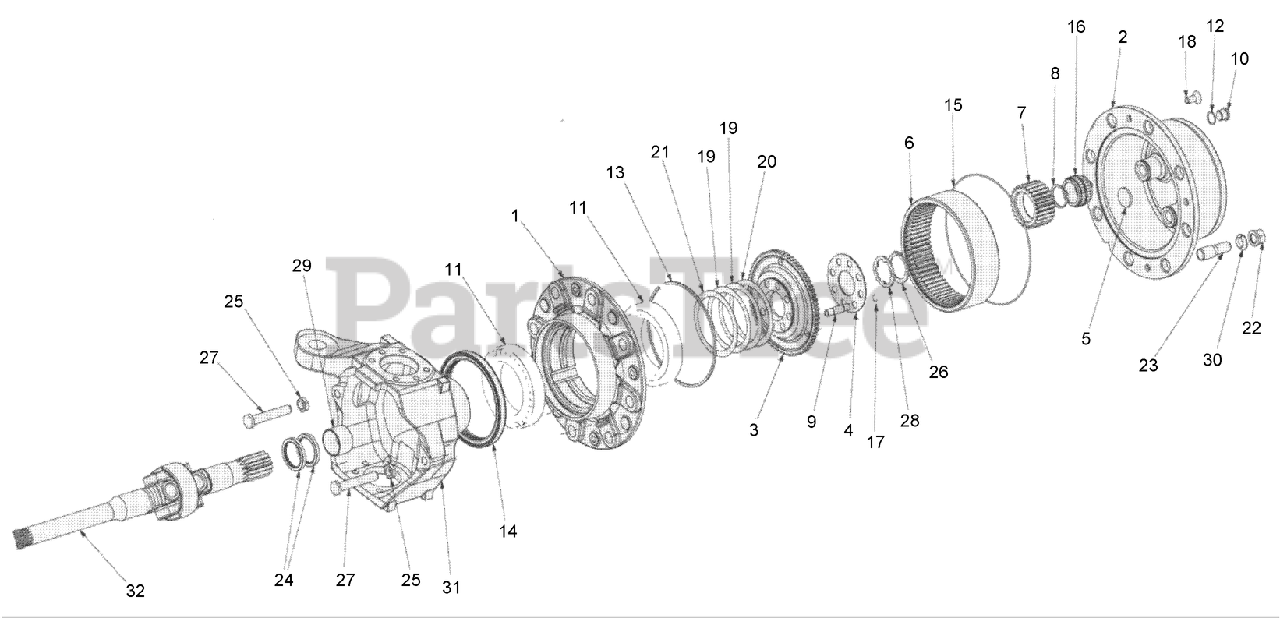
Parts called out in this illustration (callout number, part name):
1	HUB-WHEEL
2	HUB-Planetary
3	FLANGE-Crown
4	RING-Crown
5	SHIM-Crown Wheel
6	WHEEL-Crown
7	GEAR-Planetary
8	RING-SNAP
11	Bearing
12	WASHER-Copper
13	RING-Internal Retaining
15	O-RING
26	RING-SNAP
27	SCREW-Steering, End
28	SHIM-Crown
29	Bushing
30	WASHER-Elastic
31	JOINT-LH, Articulated
